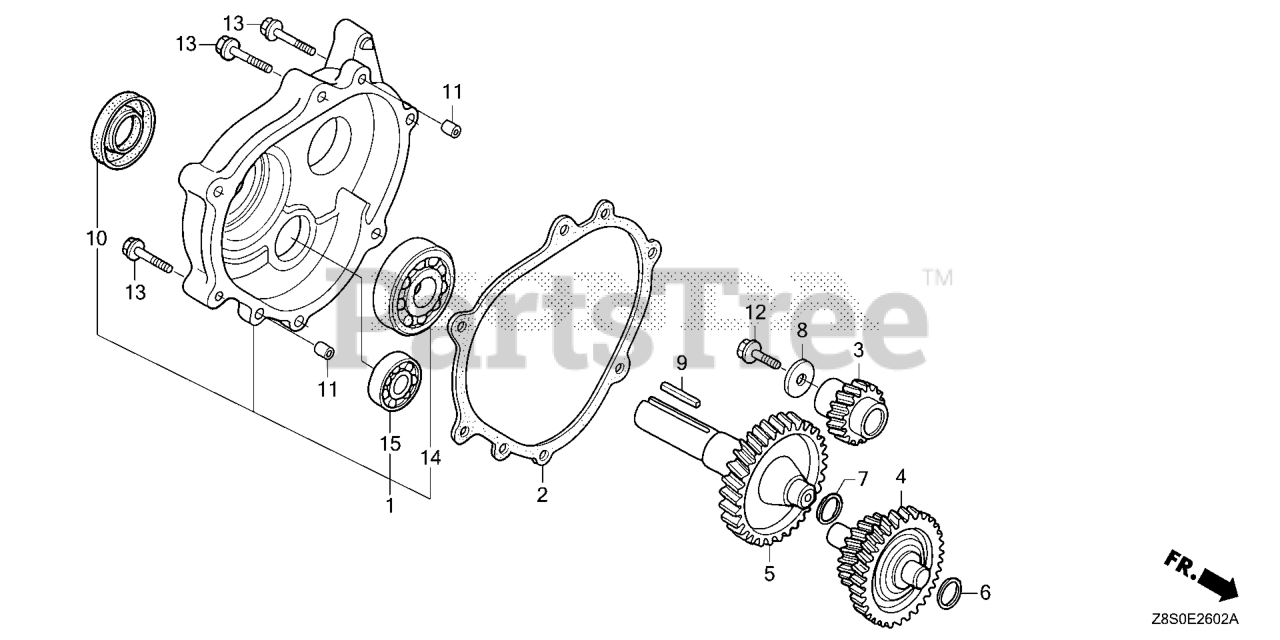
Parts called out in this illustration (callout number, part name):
1	COVER ASSY., REDUCTION CASE
2	GASKET, CHAIN CASE COVER
3	GEAR, PRIMARY DRIVE (17T)
4	COUNTERSHAFT
5	SHAFT, P.T.O. (H-TYPE)
6	SHIM A
7	SHIM B
8	WASHER (8MM)
9	KEY (6.3X6.3X43)
10	OIL SEAL (30X46X8) (NOK ASIA)
11	PIN A, DOWEL (8X14)
12	BOLT, FLANGE (8X25)
13	BOLT, FLANGE (8X40) Use up to Engine SN 1003236.
14	BEARING, RADIAL BALL (6206)
15	BEARING, RADIAL BALL (6302)
